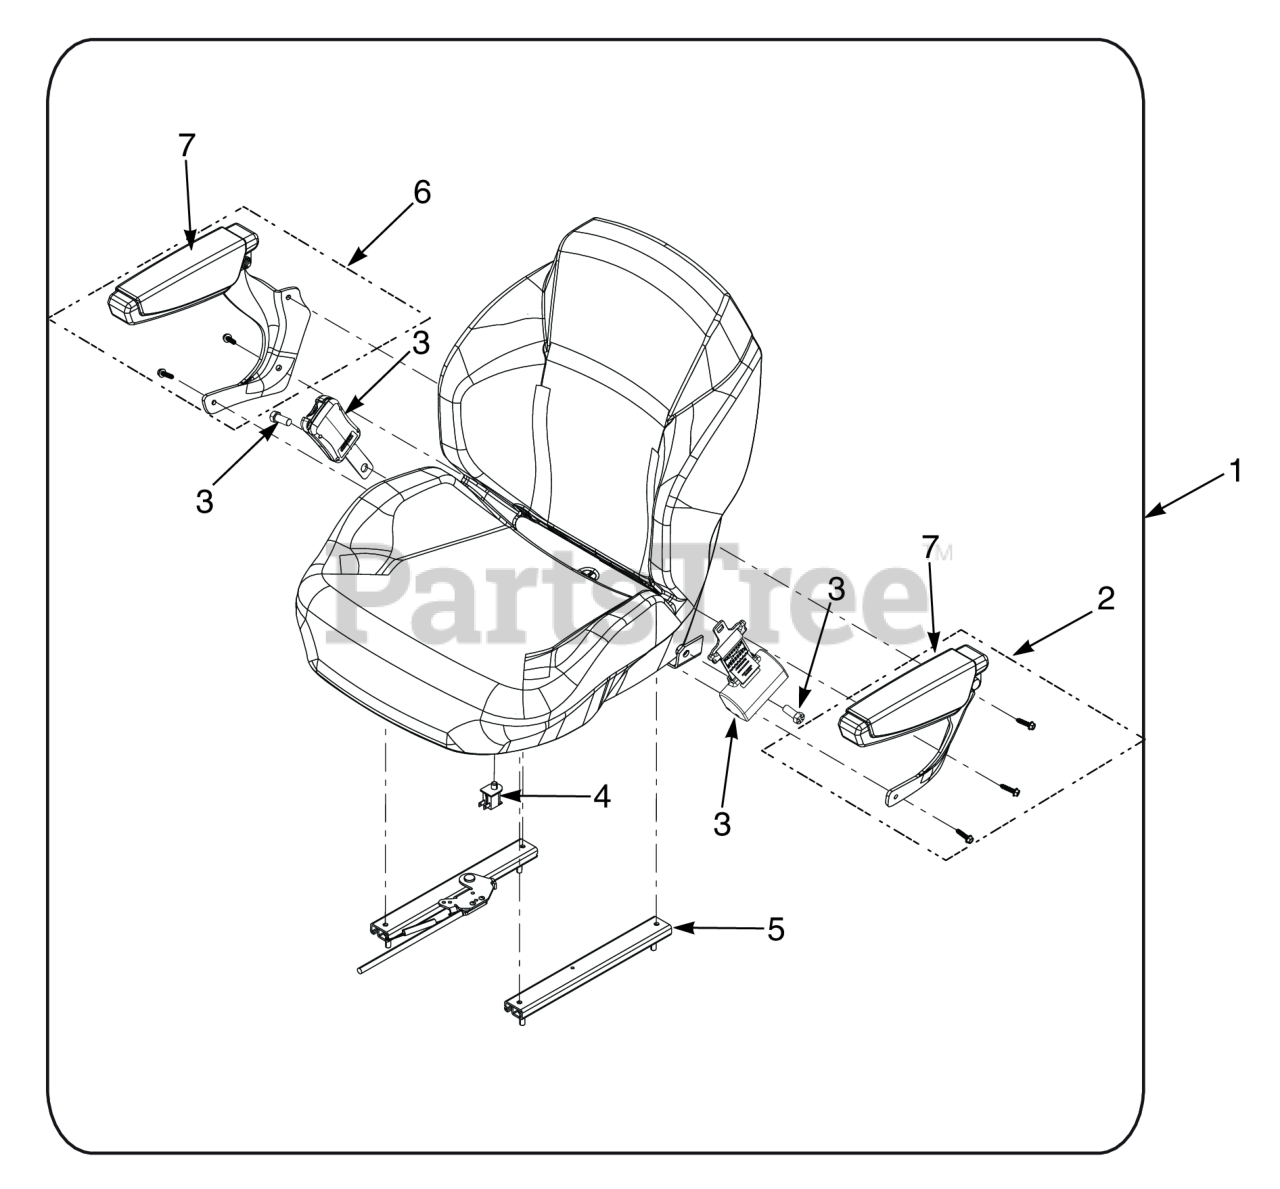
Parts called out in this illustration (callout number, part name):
1	Seat Assembly (INCL 14)
2	Armrest Kit, LH
3	Seat Belt Kit, Retractable - SCZII
4	Switch, Interlock, Normally Open
5	Track Kit
6	Armrest Kit, RH
7	Pad, Armrest
